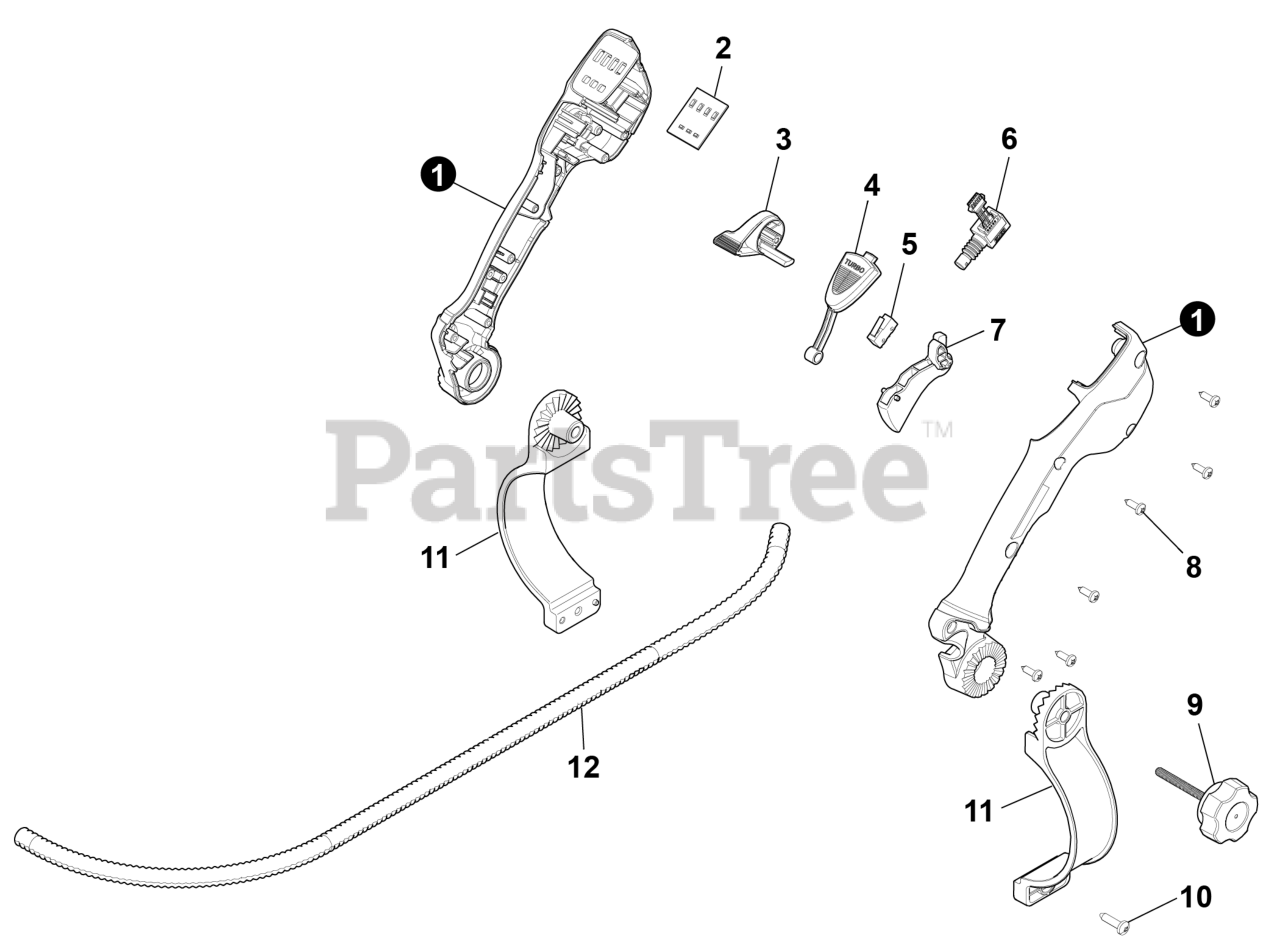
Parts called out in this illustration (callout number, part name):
1	HANDLE,CONTROL-SET
2	DISPLAY,LED
3	KNOB, CRUISE CONTROL
4	BUTTON, TURBO
5	SWITCH, MICRO
6	SWITCH,SPEED CONTROL
7	LEVER,THROTTLE
9	SCREW,KNOB
11	CLAMP,THROTTLE MOUNT
12	HARNESS,WIRING
